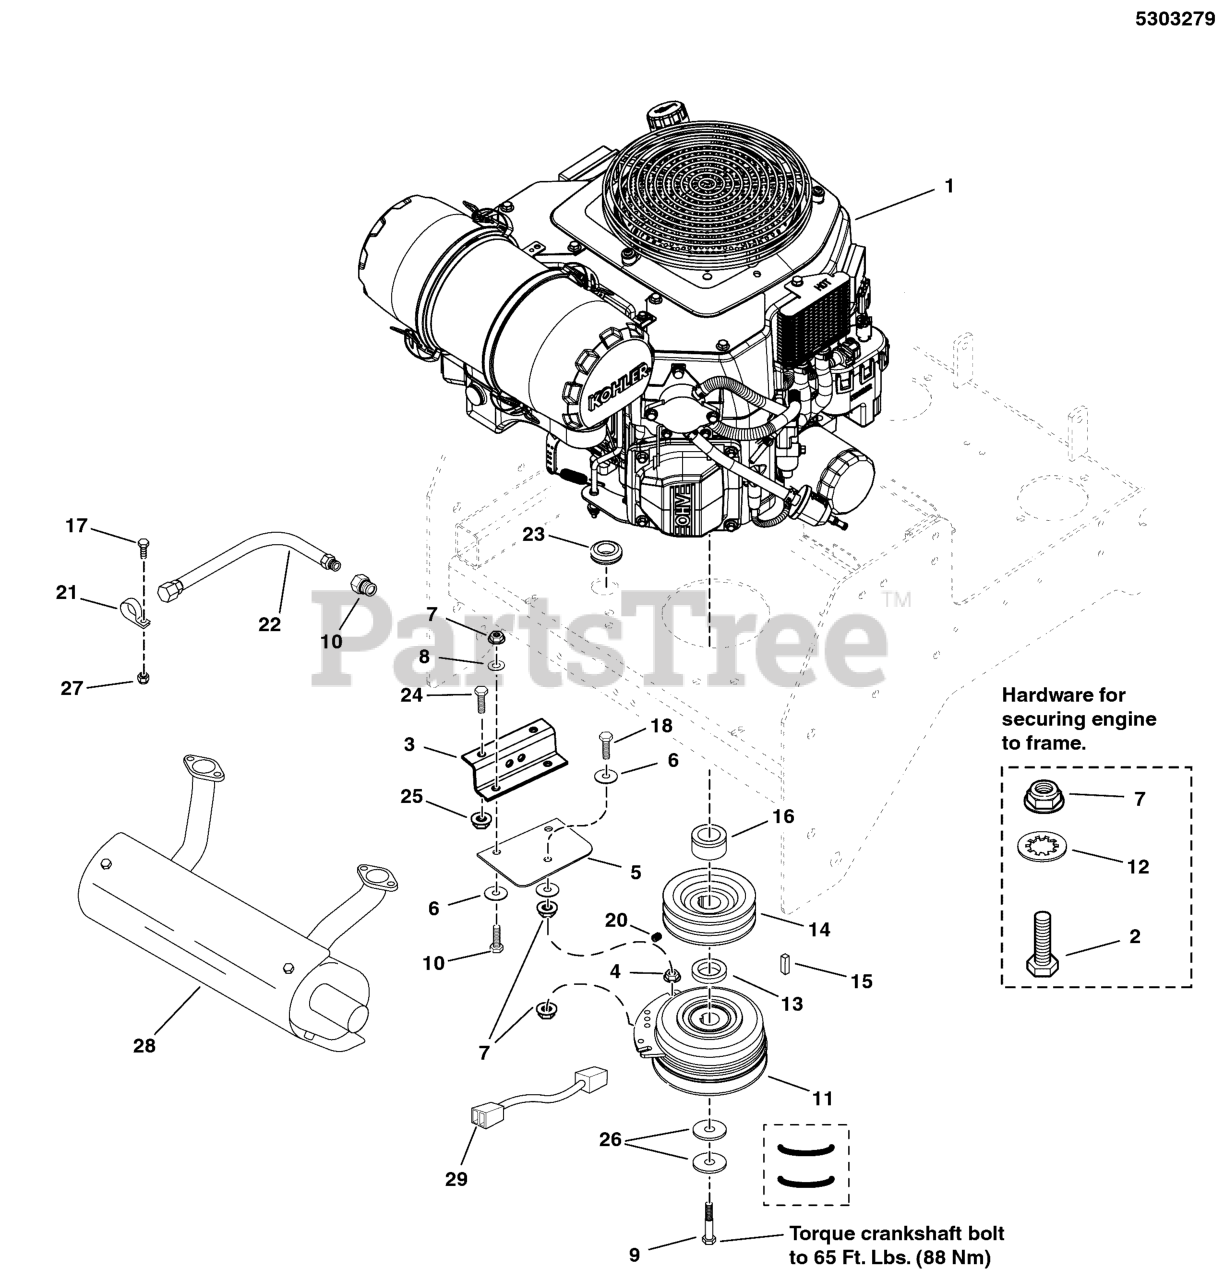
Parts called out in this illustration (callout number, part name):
2	BOLT, 5/16-18 X 1-3/4 GD5 YZ
3	ANCHOR, CLUTCH - BLK
4	NUT, 5/16-18 HEX SERRATED FLANGE (LARGE)
5	CLUTCH ANCHOR PAD
6	WASHER-3/8 FENDER
7	NUT, 5/16-18 HEX NYLOCK FLANGE
8	WASHER, 5/16" SAE
9	BOLT, CRANKSHAFT,7/16-20X2-3/4, GD8
10	BOLT, 5/16-18 X 1 GD5 YZ
11	CLUTCH,5218-221, WARNER
12	WASHER, 5/16 INT. TOOTH LOCK
13	SPACER, 1.13 X 1.75 X .32
14	PULLEY, CRANKSHAFT, 1.126 ID X 4.75 OD
15	KEY, 1/4 SQ X 1
16	SPACER, 1.13 X 1.75 X 1.03, CZ
17	BOLT, 1/4-20 X 1" GD5 CZ
18	BOLT, 5/16-18 X 2-1/4 TFL, GD5 YZ
20	SET SCREW, 5/16-18 X 3/8, KNURL
21	CLAMP, VINYL INSULATED
22	HOSE, OIL DRAIN
23	GROMMET, 7/8
24	BOLT, 3/8-16 X 1" GD5 CZ
25	NUT, 3/8-16 HEX NYLOCK FLANGE
26	BELLEVILLE WASHER 1.1875 X .442 X .089
27	NUT, 1/4-20 HEX NYLOCK FLANGE
28	MUFFLER, KOHLER EFI, OIL FILTER SIDE
29	CLUTCH JUMPER W/ DIODE, WARNER
